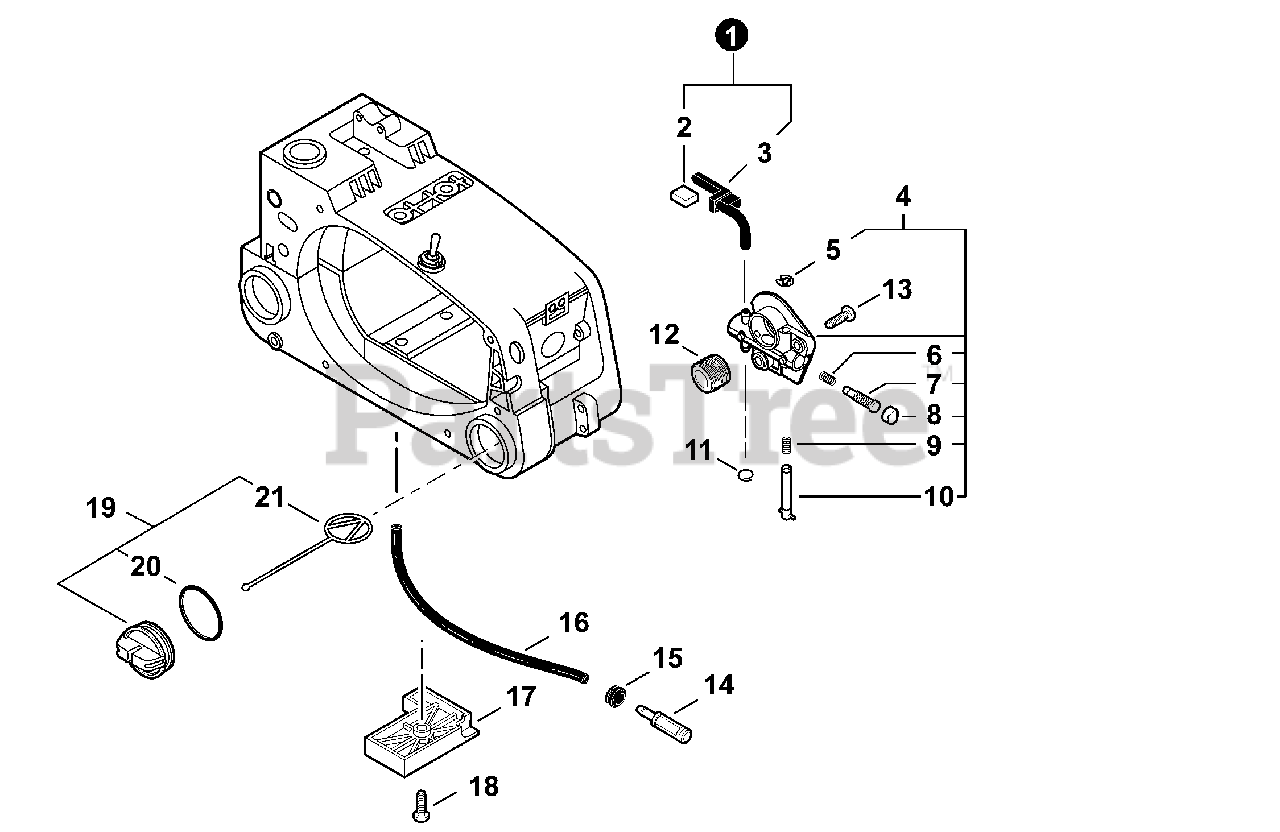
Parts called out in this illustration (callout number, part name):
1	PIPE KIT, OIL
2	PAD, FOAM
3	PIPE, OIL OUTLET
4	AUTO-OILER ASSY
7	PLUNGER ASSY
8	CAP, PLUNGER
10	ADJUSTER, OILER
11	CLIP Ø6.5 MM
12	GEAR, WORM
13	SCREW 5×12
14	FILTER, OIL
15	GROMMET
16	PIPE 3×6×115 BLACK
17	COVER, BOTTOM
18	SCREW 4×16
19	CAP ASSY, OIL - BLACK
21	CONNECTOR, CAP L= 60 MM
